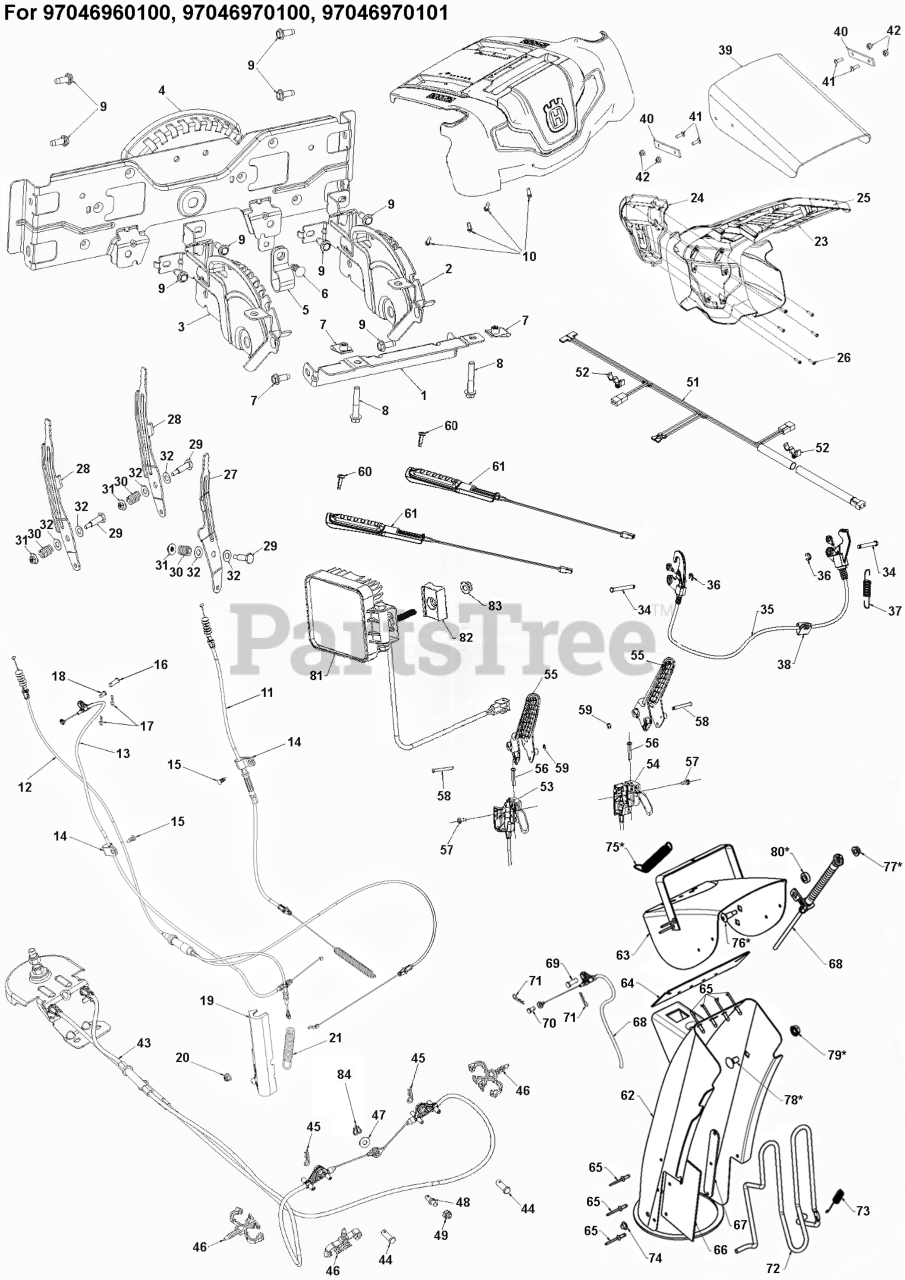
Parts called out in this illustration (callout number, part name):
4	Brackets
5	CLIP.CABLE.BLK
6	FASTENER.PUSH.O.250X0.783
7	NUT.U-CHNL.1/4-20.550DP.350PNL
8	1/4-20 U NUT
9	SCREW 14-20 X 5/8
10	HEX.WASHER.HEAD 1/4-20 X .65
11	Cables
12	CABLE IMPELLER
13	Cables
14	CLIP.CABLE.BLK
15	FASTENER.PUSH.O.250X0.783
16	PIN CLEVIS 5/16X.875
17	HAIRPIN.SOFT.ZINC.059X1.125
18	PIN CLEVIS .25 X .31
19	COVER AUGER CABLE
20	NUT HEXAGON FLANGE 5/16-18 ST
21	SPRING EXTENSION; AUGER EXTENS
28	LEVER.CONTROL.SPEED/DEFLEC.BLK
29	BOLT SHOULDER_HEX HD_1/4-20_3/
30	SPRING.COMPRESSION.82LBS
31	NUT HEX_LRG FLG_1_4-20_LOCK
32	WASHER, NYLON FRICTION
34	PIN.GROOVED
35	CABLE INTERLOCK CONTROL ACETAL
37	SPRING RETURN_INTERLOCK_DSST
38	CLIP.CABLE.BLK
39	SHIELD.DEFLECTOR.BLACK.SNOW
40	STRAP.DEFLECTOR.SHEILD
41	SCREW.MACHINE.8-32 X 1/2-BLK
42	NUT.HEX.NYLOCK
44	PIN CLEVIS 5/16X.875
45	HAIRPIN.SOFT.ZINC.059X1.125
46	CLIP.CONDUIT.DOUBLE LOOP
47	WASHER FLAT_.250 X .625 X .06
48	Clevis Pins
49	NUT HEXAGON 1/4-20 ST ZPB
53	CABLE.POWER STEERING.LHS
54	CABLE.POWER STEERING.RHS
55	LEVER ENGAGMENT
56	SCREW HEX_WASH_13-16 X 1.50_H
57	SCREW 14-20 X 5/8
58	PIN.GROOVED
60	SCREW.PAN.HD.TORX.1/4-20X.750
61	GRIP.HANDLE.HEATED
62	ASM.CHUTE/DEFLECTOR.668
69	PIN CLEVIS 5/16X.875
70	PIN CLEVIS .25 X .31
71	HAIRPIN.SOFT.ZINC.059X1.125
72	GUARD ROD CHUTE GUARD SHORT CL
73	SPRING.CHUTE.GUARD
74	NUT
81	LED LIGHTS
82	MOUNTING BRACKET LIGHT MOUNTIN
83	NUTNYLOK.FLRANGE.5/16-18
83	NUT HEXAGON FLANGE 5/16-18 ST
